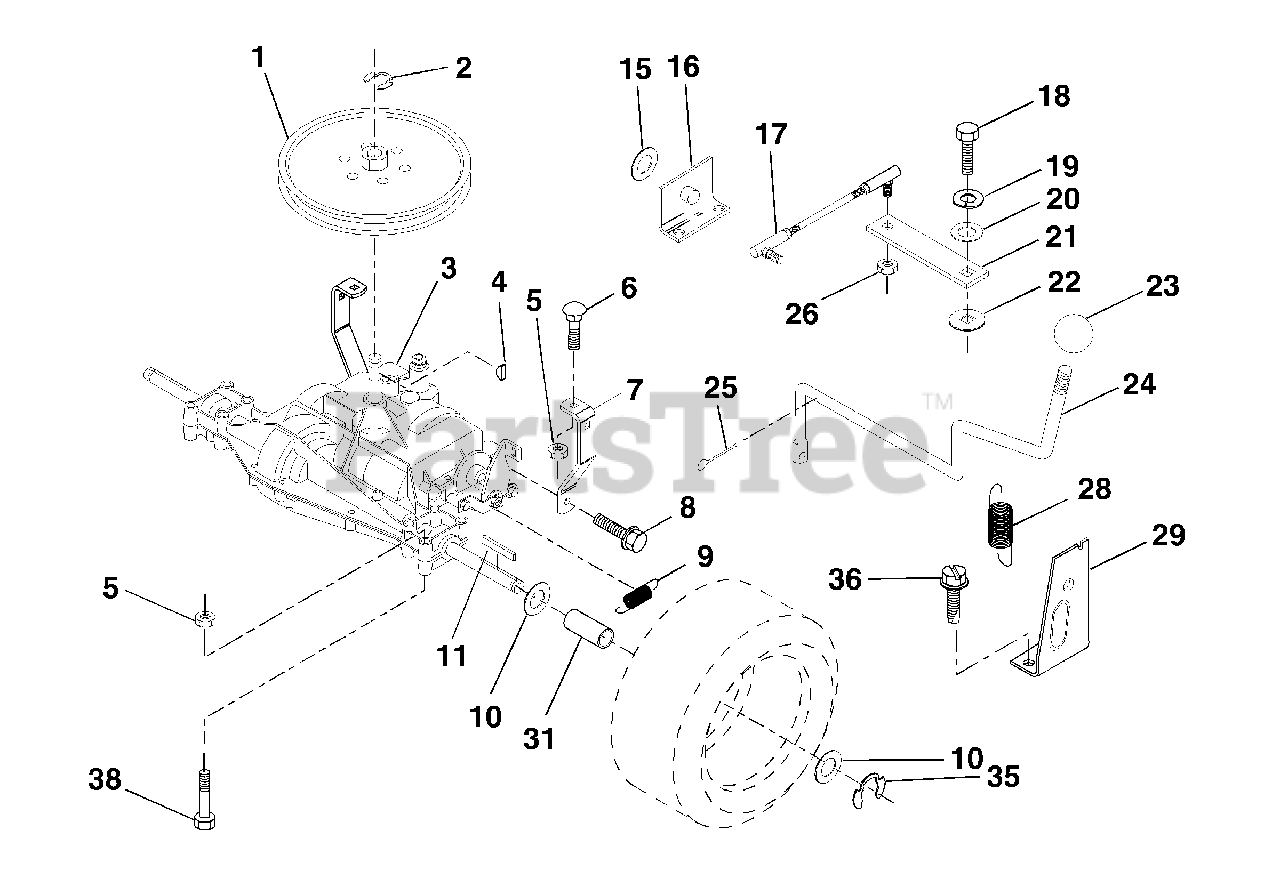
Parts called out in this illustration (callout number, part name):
2	Ring, Retainer
3	Transaxle, Peerless Model No. 205-507B
4	Key, Woodruff #9
5	Nut, Crownlock 5/16-18
6	Bolt, Carriage 5/16-18 UNC x 3/4
7	Strap, Torque
8	Screw 5/16-18 x 3/4
9	Spring, Brake
10	Washer 25/32 x 1-1/4 x 16 Ga.
11	Key, Square
15	Washer 17/32 x 1 x 16 Ga.
16	Support Handle Shift LH
17	Link, Shift
18	Bolt, Fin Hex 1/4-28 UNF x 3/4 Gr. 8
19	Washer, Lock 1/4
20	Washer 9/32 x 3/4 x 10 Ga.
21	Arm, Shift
22	Washer, Shift Plate
23	Knob, Rd 1/2-13
25	Pin, Cotter 1/8 x 1
26	Locknut 5/16-24 UNF
28	Extension, Spring
29	Support Handle Shift RH
31	Spacer Axle
36	Screw, Thd. Cut 1/4-20 x 1/2
38	Bolt, Hex Hd 5/16-18 x 2-3/4
